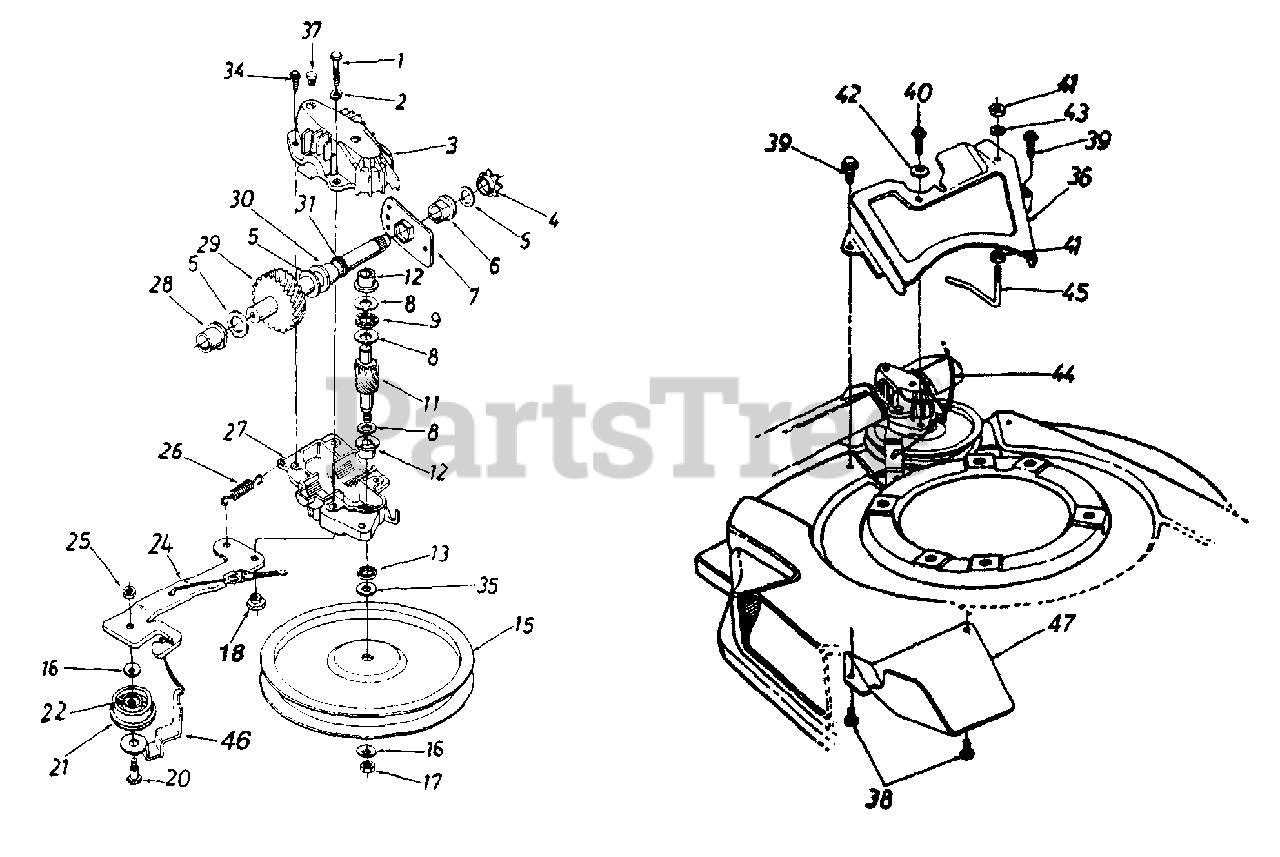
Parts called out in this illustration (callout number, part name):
1	Hex Bolt 1/4-20 x 1.25" Lg.
2	L-Wash. 1/4" I.D.
3	Upper Hsg. Half
4	#48 Sprocket 7 Tooth x 1/2 Pitch
5	Fl-Wash. 5/8" I.D. x .030
6	Hex Flange Brg. .631" I.D.
8	Thrust Wash. .382" I.D. x .70" O.D.
9	Thrust Bearing .375" I.D. x .812" O.D.
11	11 Tooth Helical Gear
12	Flange Bearing
13	Oil Seal
15	Fl-Pulley 5.06" I.D.
16	Bell-Wash. .265" I.D. x.75"
17	Hex Nut 1/4-28 L.H. Thd.
18	Shld. Spacer .375" Dia. x .170
20	Shld. Bolt .375" Dia. x .40"
21	Fl-Idler Plastic 1.50" Dia.
22	Needle Brg. .375" x .375"
24	Idler Brk't. Ass'y.
25	Hex Patch L-Nut 1/4-28 Thd.
26	Extension Spring 1.12" Lg.
27	Lower Hsg. Half
28	Flange Bearing .56 Dia.
29	Shaft Ass'y.
30	Flange Bearing .629 Dia.
31	Oil Seal .625 Dia.
34	Scr. AB #10-16: .750 Hxlnd Wsh.
35	Hex Washer .26" x .88"
38	Hex B-Tap Scr. 1/4-20: .375 Lg.
39	Hex AB-Tap Scr. 1/4 x .50" Lg.
40	Hex B-Tap Scr. 1/4 x .62" Lg.
41	Hex Nut 1/4-20 Thd.
42	Bell-Wash. .265" I.D. x.75"
43	L-Wash. 1/4" I.D.
44	S.P. Cable - 48" Lg.
45	S.P. Belt Guard
46	Belt Guard
